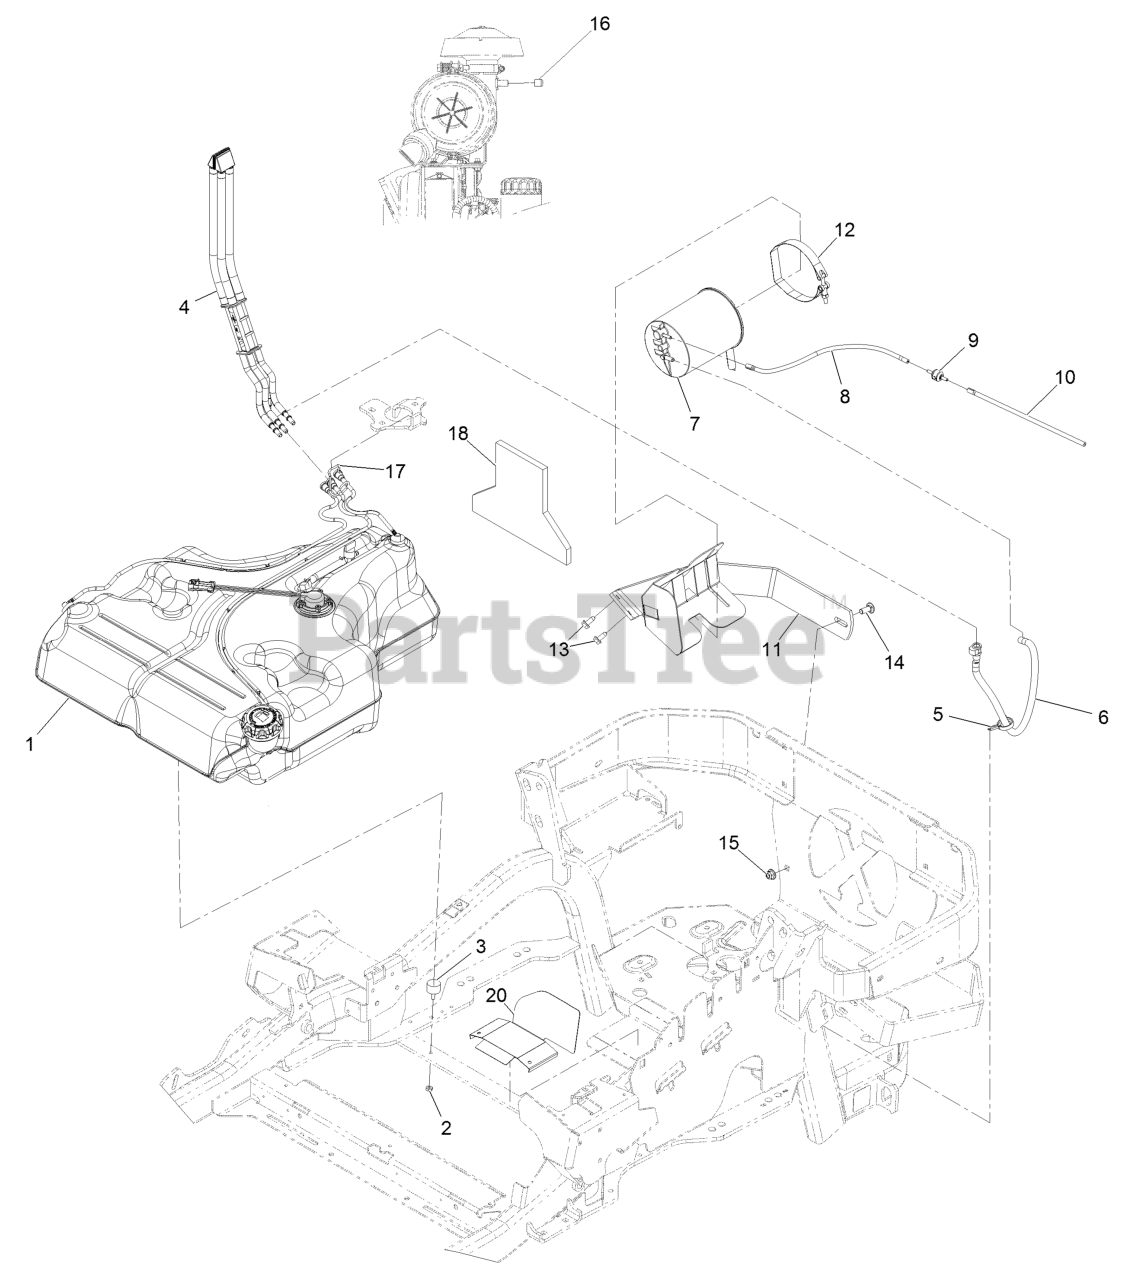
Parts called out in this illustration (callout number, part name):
2	NUT-JAM
4	FUEL MANIFOLD VENT ASM
5	CLAMP-HOSE
6	VENT HOSE ASM
7	CANISTER-CARBON, 1200CC
8	HOSE-VENT, FORMED
10	HOSE-VENT, FORMED
11	MOUNT-CANISTER
12	CLAMP, T-BOLT
13	Screw-HWH 5/16-18 X 3/4 Tf
14	SCREW-CARR
15	NUT-HF, NI
16	PLUG-PORT
17	RETAINER-LINE, VAPOR
18	INSULATION-FOAM, FUEL TAN
20	GUARD-EXHAUST
